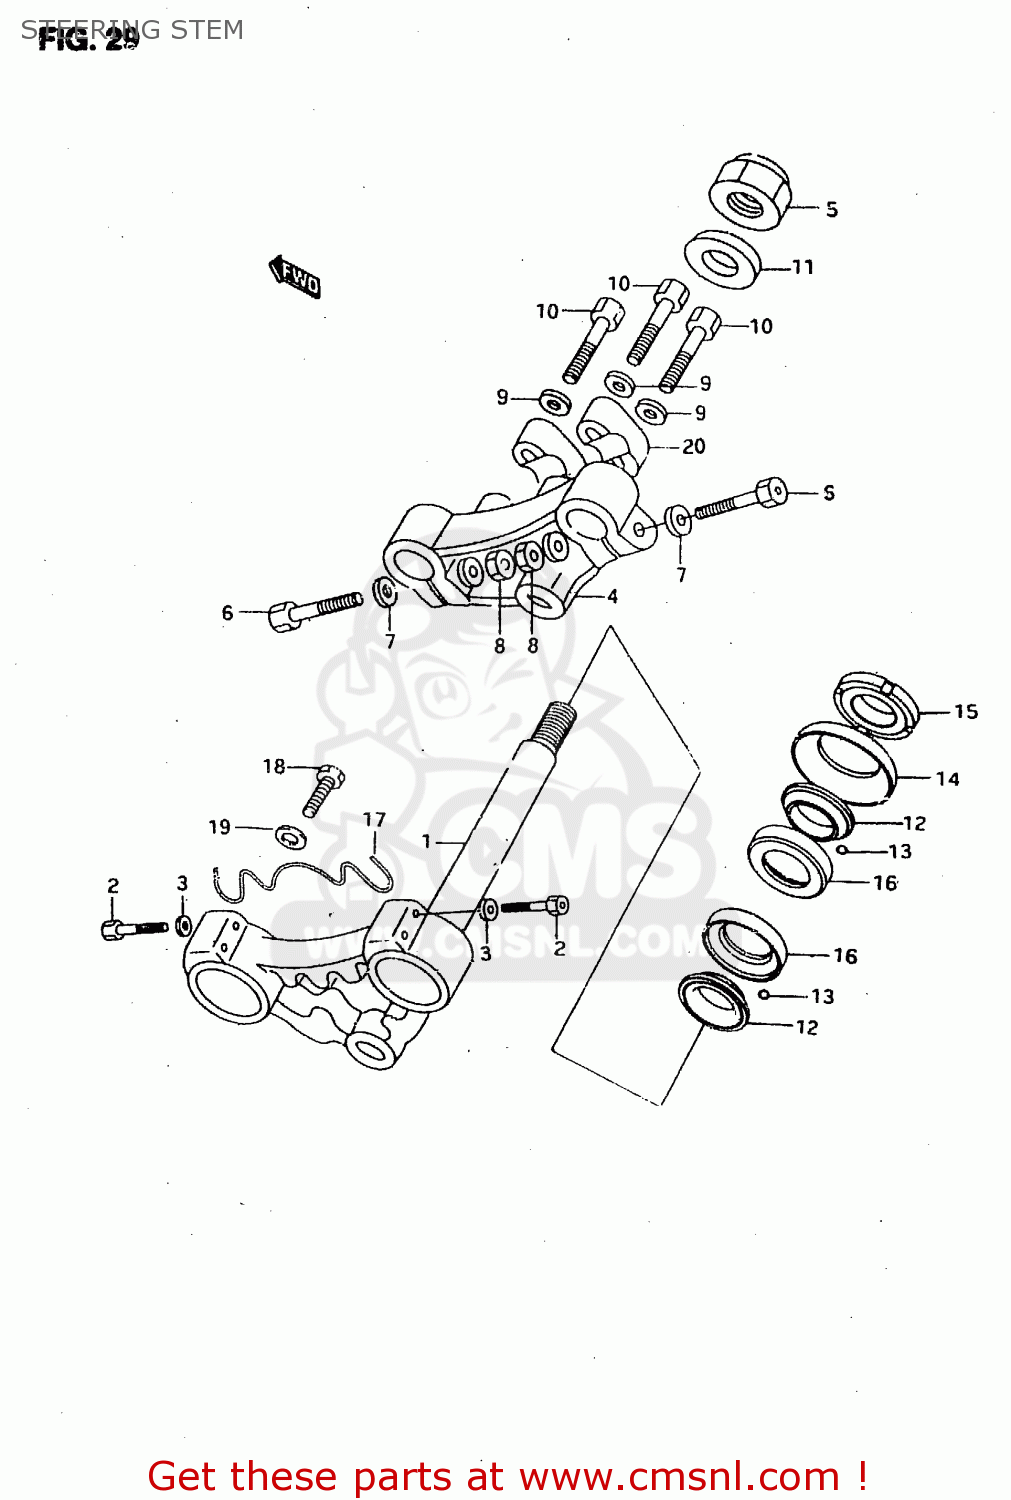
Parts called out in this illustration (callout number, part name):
1	STEM, STEERING
2	BOLT
3	WASHER
4	HEAD, STEERING STEM
5	NUT
6	BOLT
7	WASHER
8	NUT
9	WASHER
10	BOLT
11	WASHER
12	RACE,STEERING OUTER UPR
13	BALL 3/16
14	DUST SEAL,STEERING UPR
15	NUT, STEM LOCK
16	RACE,STEERING INNER UPR
17	GUIDA, HOSE BRAKE
18	BOLT
19	WASHER
20	HOLDER, HANDLE
